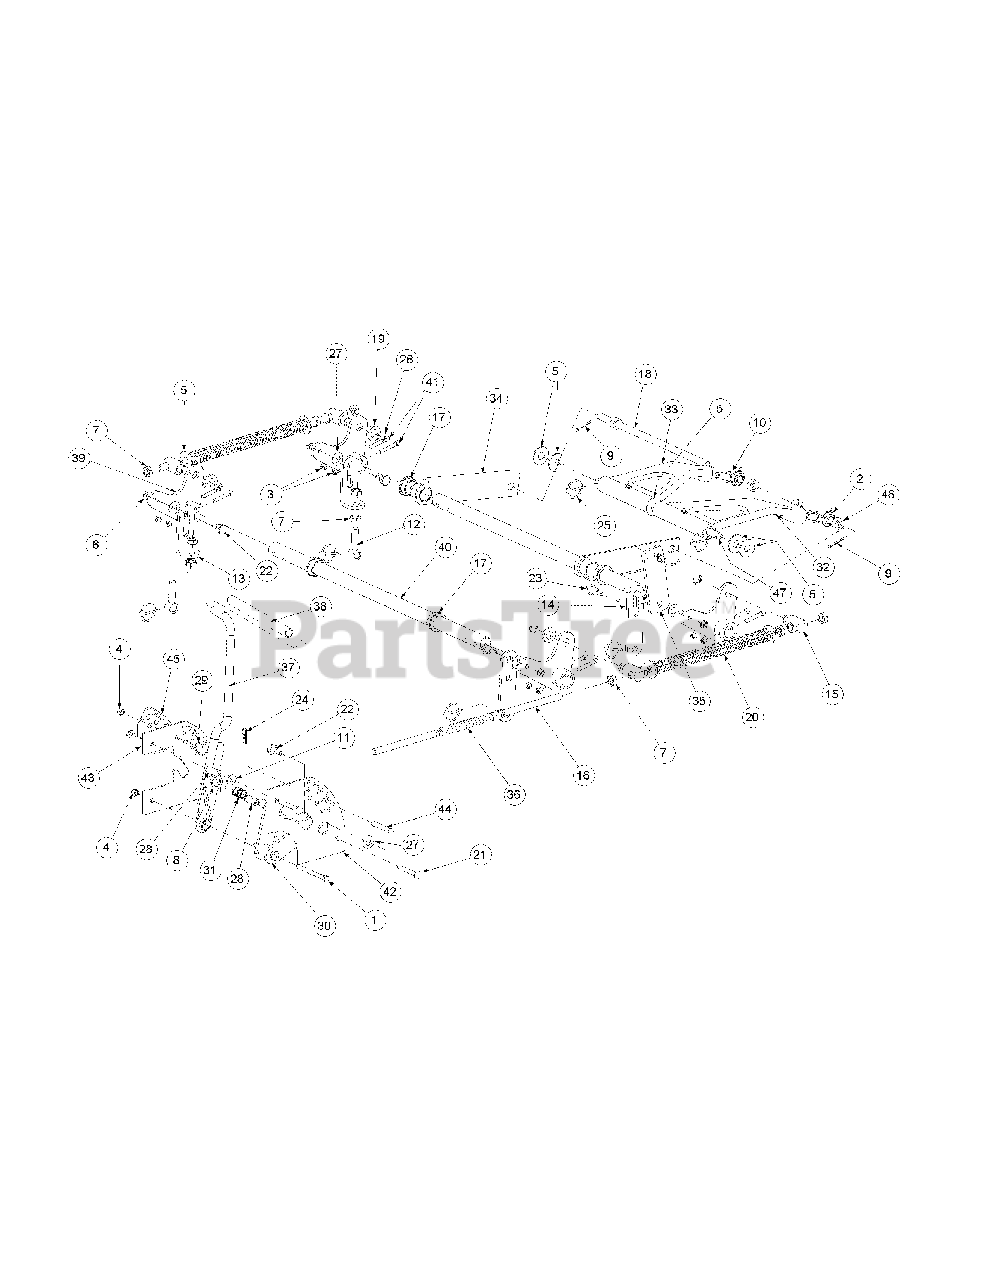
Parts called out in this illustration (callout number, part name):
1	Hex Cap Screw, 3/8-16, 3.75
2	Rod End, Male
3	Nut, 5/16-18, Nylock
4	Nylock Insert Lock Nut, 3/8-16
5	Flat Washer, 5/8
6	Hex Nut, Flange Lock, 3/8-16
7	Jam Nut, 5/8-11
8	Flat Washer, .06, .776, 1.25
9	Cotter Pin, 3/16 x 1-1
10	Jam Nut, 5/8-18
11	Idler Washer
12	Eye Bolt, 5/8ID
13	Eye Bolt Mount Link, 5/8 ID
14	Deck Link
15	Ferule Lift
16	Lift Connector Rod
17	Hex Flange Bearing, 1.25 ID
18	Front Lift Link, Rod Mount
19	Spacer, .812 ID x .268 Lg.
20	Lift Compression Spring
21	Carriage Bolt, 3/8-16, 2.75
22	Shoulder Screw, 0.625 OD x .437 Lg.
23	Shoulder Screw, 0.625 OD x .830 Lg.
24	Cotter Pin, .148 x 3.00
25	Linch Pin, 3/16 Dia.
26	E Clip, 3/4 Dia.
27	Nylon Flat Washer, 5/8
28	Spacer, .39 ID x .63 OD x 1.442
29	Shoulder Screw, .50 OD x 0.27
30	Lift Pivot Assembly
31	Lift Handle Spring
32	Bearing Lift Brace Assembly, Right Hand
33	Bearing Lift Brace Assembly, Left Hand
34	Front Frame Strut Assembly
35	Lift Link Adjustment
36	Hose, 5/8 ID 13/16 OD, 8" LG
37	Lift Handle Assembly
38	Lift Handle Grip
39	Bellecrank Weldment Assembly
40	Deck Lift Shaft
41	Socket Head CapScrew, 5/16-18 x 2
42	Outer Lift Index Plate
43	Inner Lift Index Plate
44	Clevis Pin, .438 Dia. x 2.625 Lg.
45	Decal Height Indicator
46	Spacer, .630 ID x 1.06 OD x .440
47	Lift Link Rod
